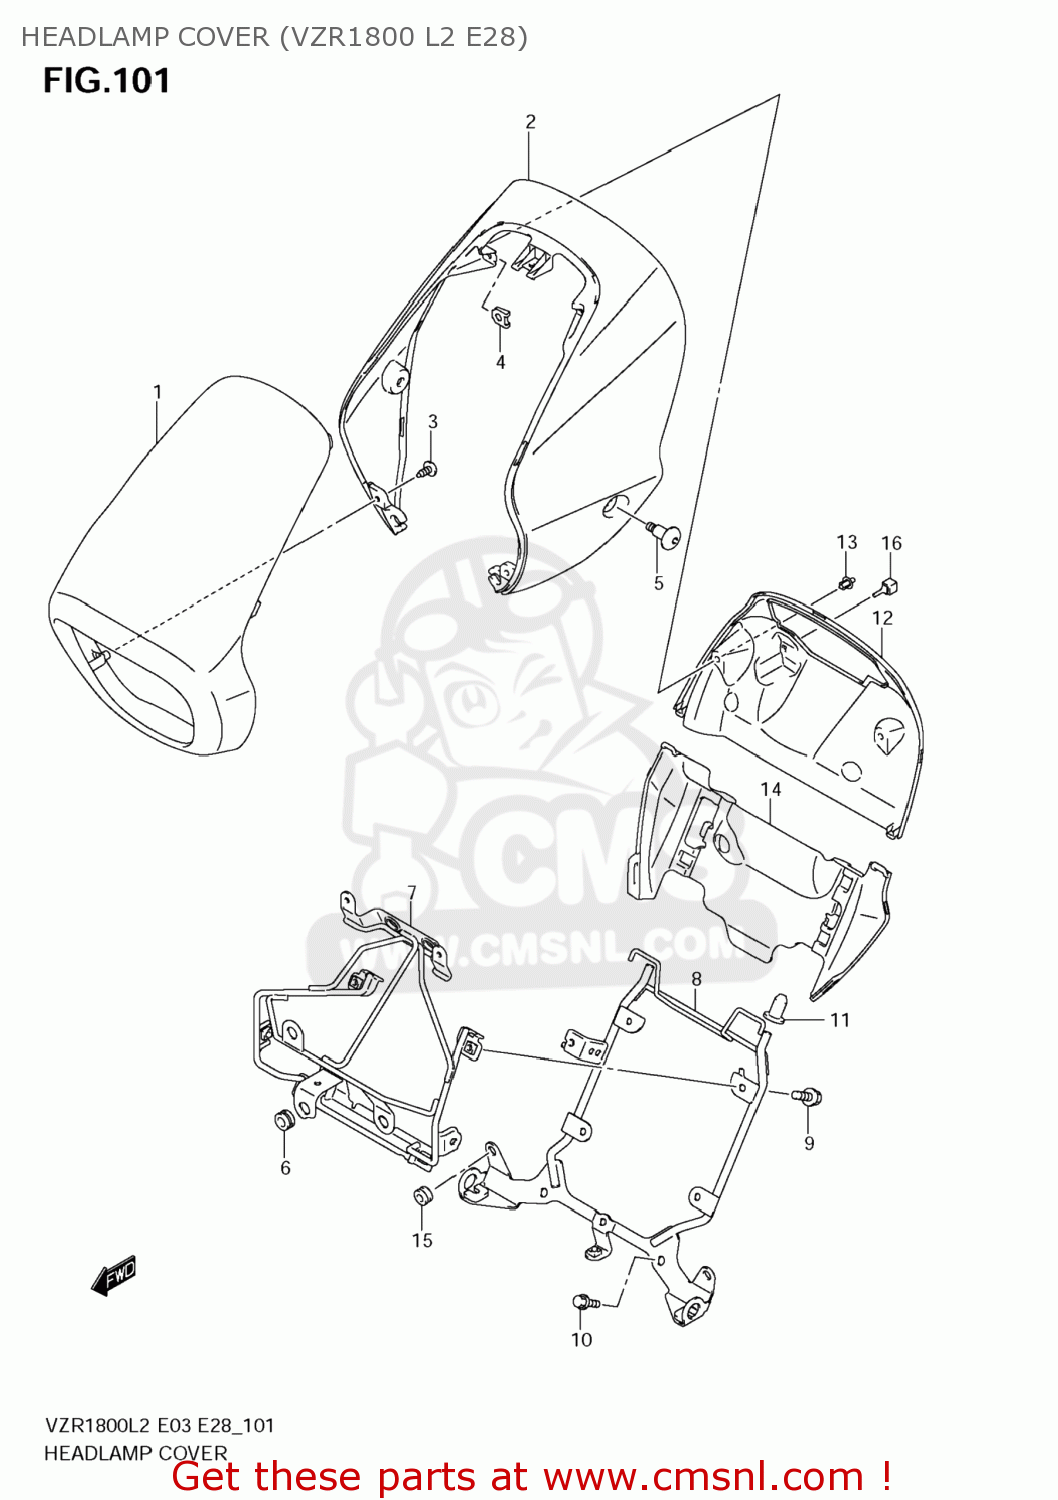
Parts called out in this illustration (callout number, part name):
1	COVER,HEADLAMP
2	COVER,HEADLAMP LWR
3	SCREW
4	NUT
5	SCREW(6X22)
6	CUSHION
7	BRACE,HEADLAMP HOUSING
8	BRACE COMP,HEA
9	BOLT
10	BOLT
11	CUSHION,HEADLAMP HOUSING BRACE
12	COVER,HEADLAMP UPR
13	CLIP(BLACK)
14	COVER,HEADLAMP HSG BRACKET
15	CUSHION
16	CUSHION,HEADLAMP COVER UPR
